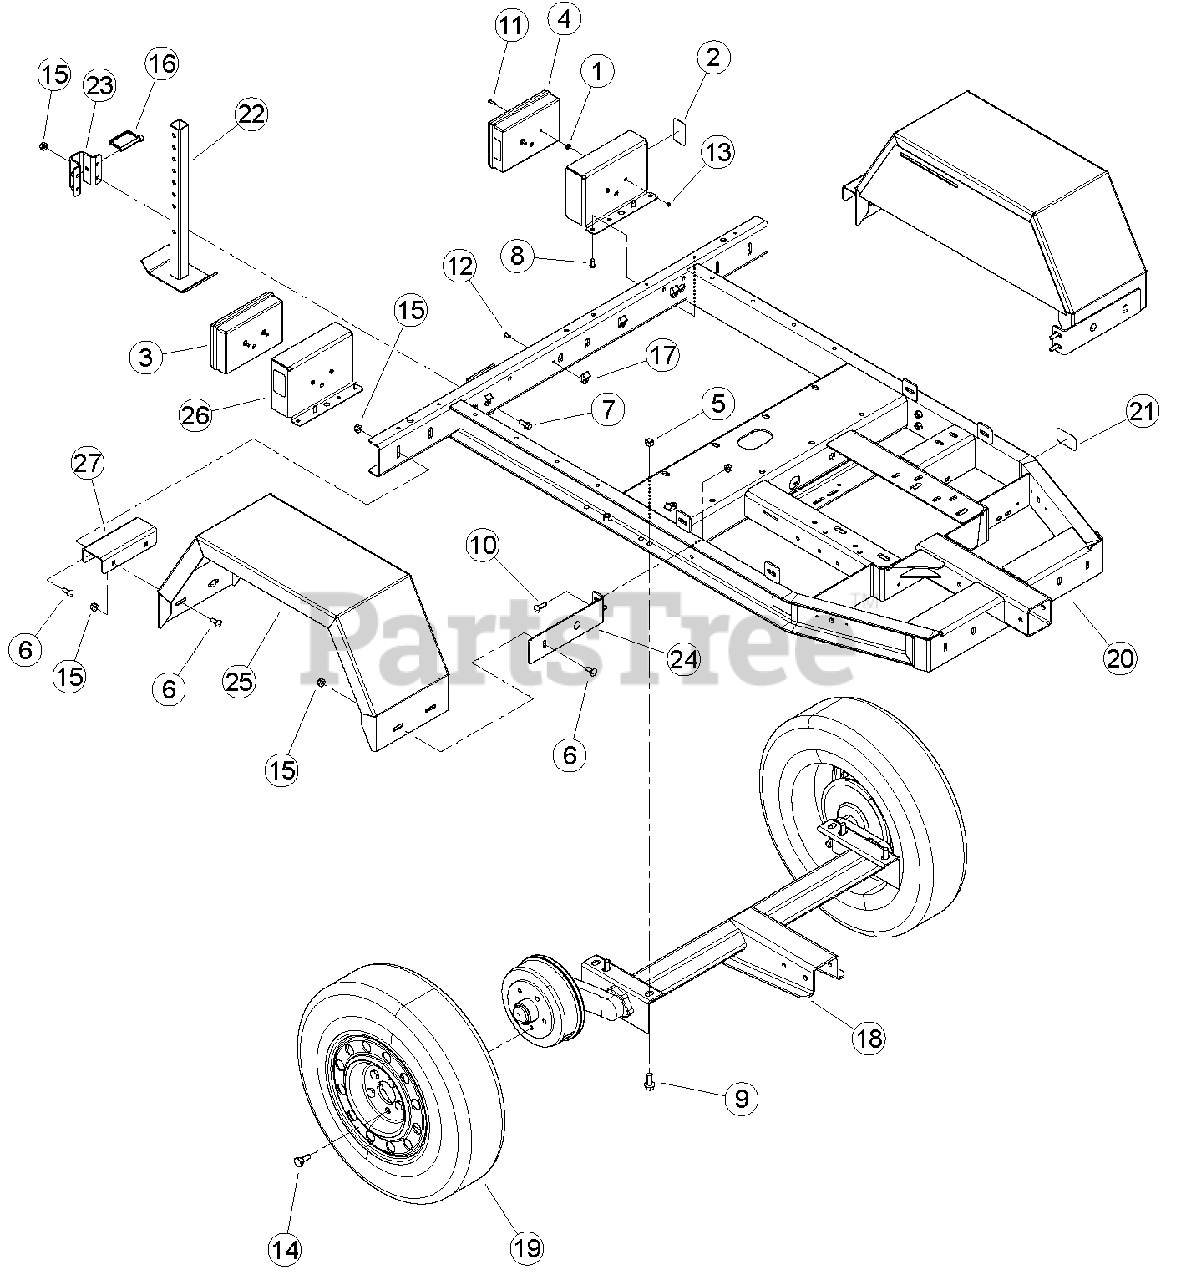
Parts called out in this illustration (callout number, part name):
1	GROMMET, 1/4 X 5/8 RUBBER
2	REFLECTOR, WIDE ANGLE RED
3	LIGHT, TAIL RH
4	LIGHT, TAIL LH
5	NUT, 1/2" CENTERLOCK GRB ZP
6	BOLT, 3/8 X 1" GR5 CRG NC ZP
7	BOLT, 3/8 X 1 FLANGE NC
8	SCREW, 11/32 X 7/8 HWH AB THREAD ZP
9	BOLT, 1/2 -13 X 1-1/4 FLANGE NC
10	BOLT, 3/8 X 1-1/4" GR5 CRG NC ZP
11	BOLT, 10-24 X 3/4" HHCS GR8 PLAIN
12	RIVET, AL BLIND 1/4 X 3/4 DOME HEAD
13	NUT, #10-24 K-LOCK ZP
14	BOLT, 12MM LUG FOR WHEELS
15	NUT, 3/8-16 NYLOCK FLANGE
16	PIN, 3/8 X 2-3/4" SNAP
17	CLAMP, CABLE MOUNT
18	AXLE, TORSION W/ BRAKES
19	WHEEL/TIRE, P205/65R15
20	ASSEMBLY, CH611DHXE/XF TRAILER W/ DECALS VIN
21	REFLECTOR, WIDE ANGLE AMBER
22	WELDMENT, REAR STABILIZER
23	GUIDE, TRAILER SUPPORT
24	BRACKET, FENDER
25	WELDMENT, CHIPPER FENDER
26	BRACKET, TAIL LIGHT
27	PLATE, FENDER SPACER
